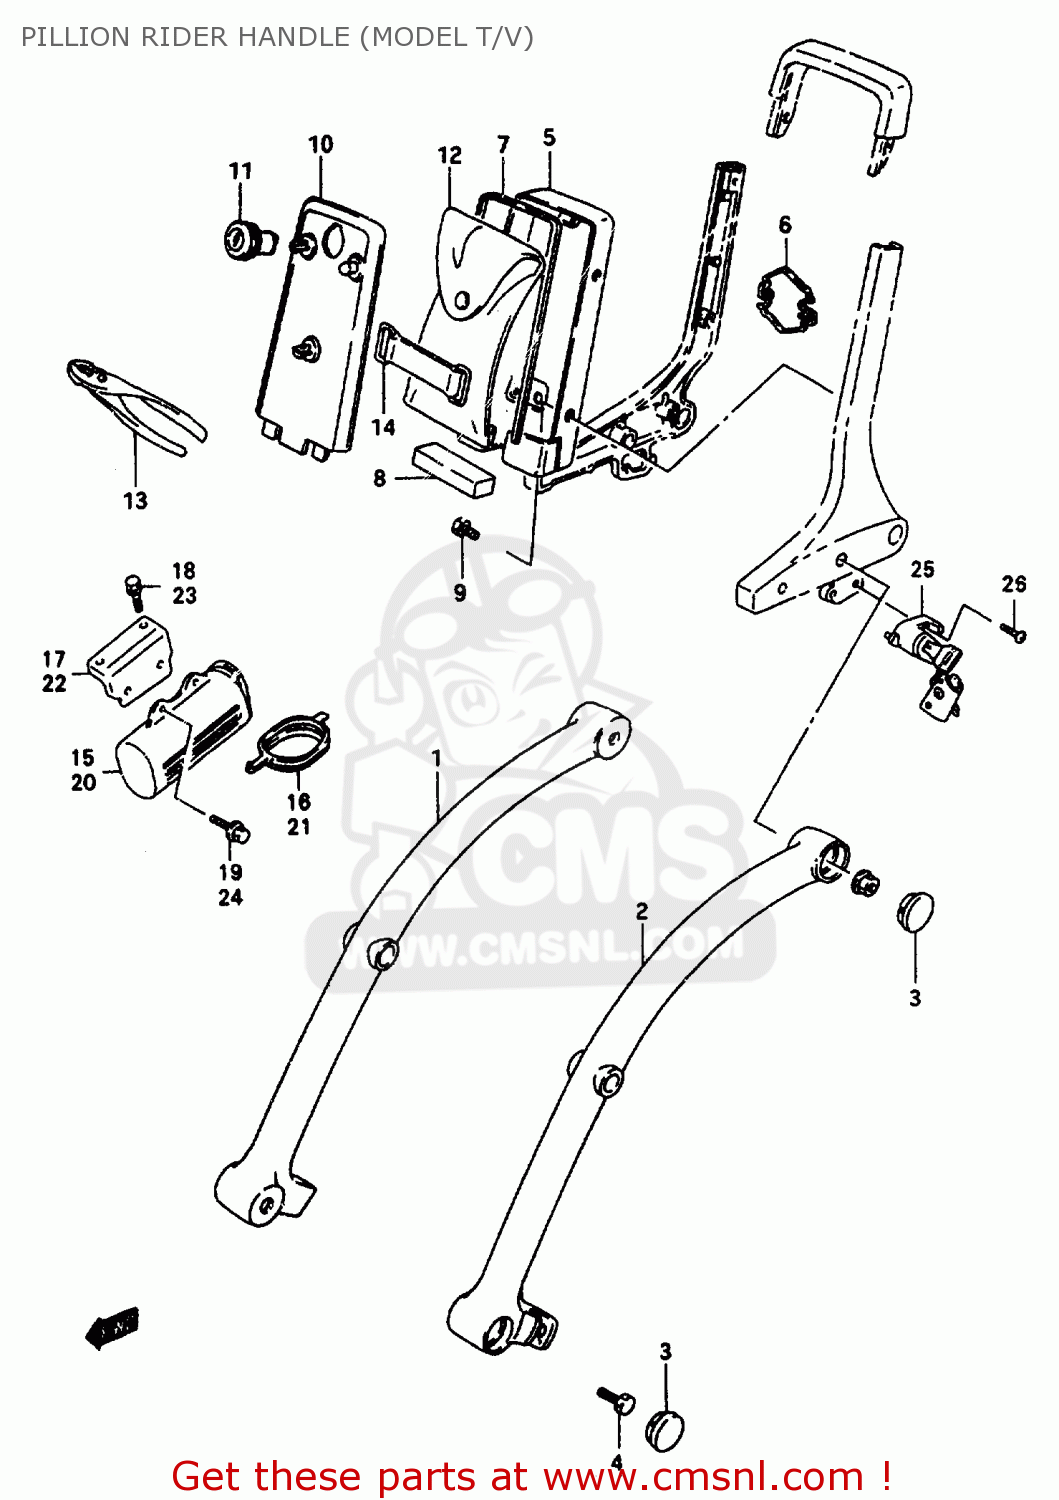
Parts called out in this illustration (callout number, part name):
1	GRIP,FRAME HANDLE RH
2	GRIP,FRAME HANDLE LH
3	CAP,FRAME HANDLE GRIP
4	BOLT
5	HOLDER,TOOL,REAR
6	EMBLEM,TOOL HOLDER RR
7	MOLDING,TOOL HOLDER RR
8	CUSHION,TOOL BACK
9	BOLT
10	HOLDER,TOOL FR
11	LOCK SET,TOOL HOLDER
12	TOOL ASSY
13	PLIER(150)
14	BAND
15	HOLDER,TOOL
16	CAP,HOLDER
17	PLATE, TOOL HOLDER
18	BOLT 6X16
19	BOLT(6X16)
20	HOLDER,TOOL
21	CAP,HOLDER
22	PLATE, TOOL HOLDER
23	BOLT 6X16
24	BOLT(6X16)
25	LOCK SET,HELMET
26	SCREW
